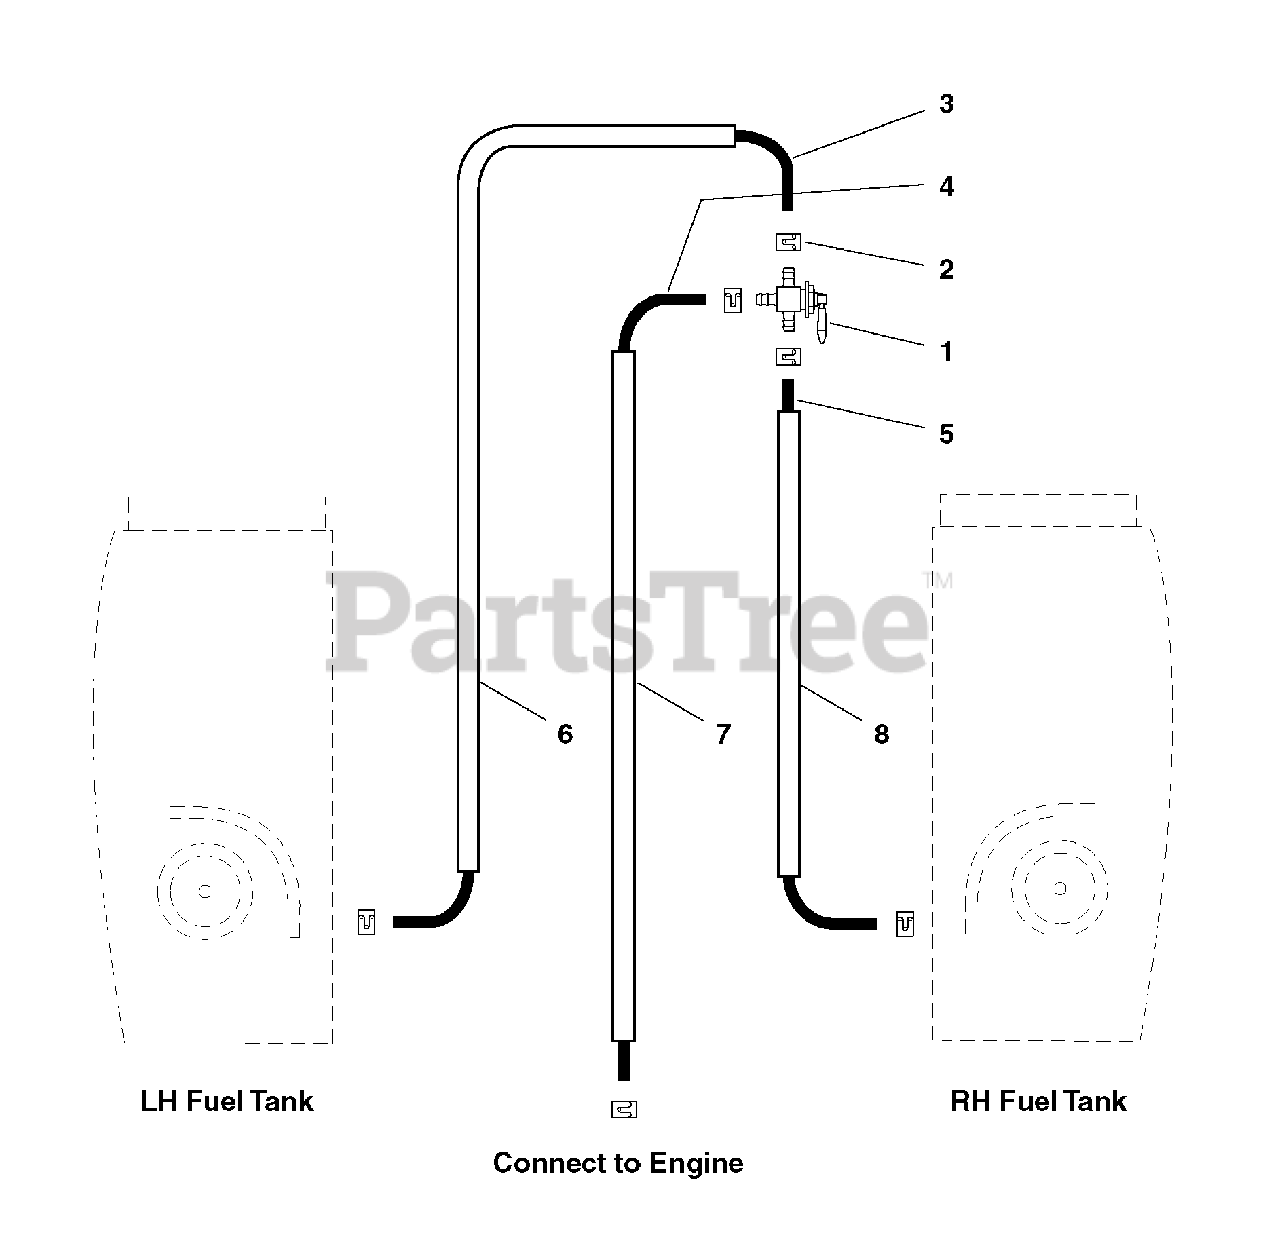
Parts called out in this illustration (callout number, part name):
1	VALVE, Fuel Shut Off
2	CLAMP, Hose
6	WIRE LOOM, 51"
7	WIRE LOOM, 33"
8	WIRE LOOM, 24"
